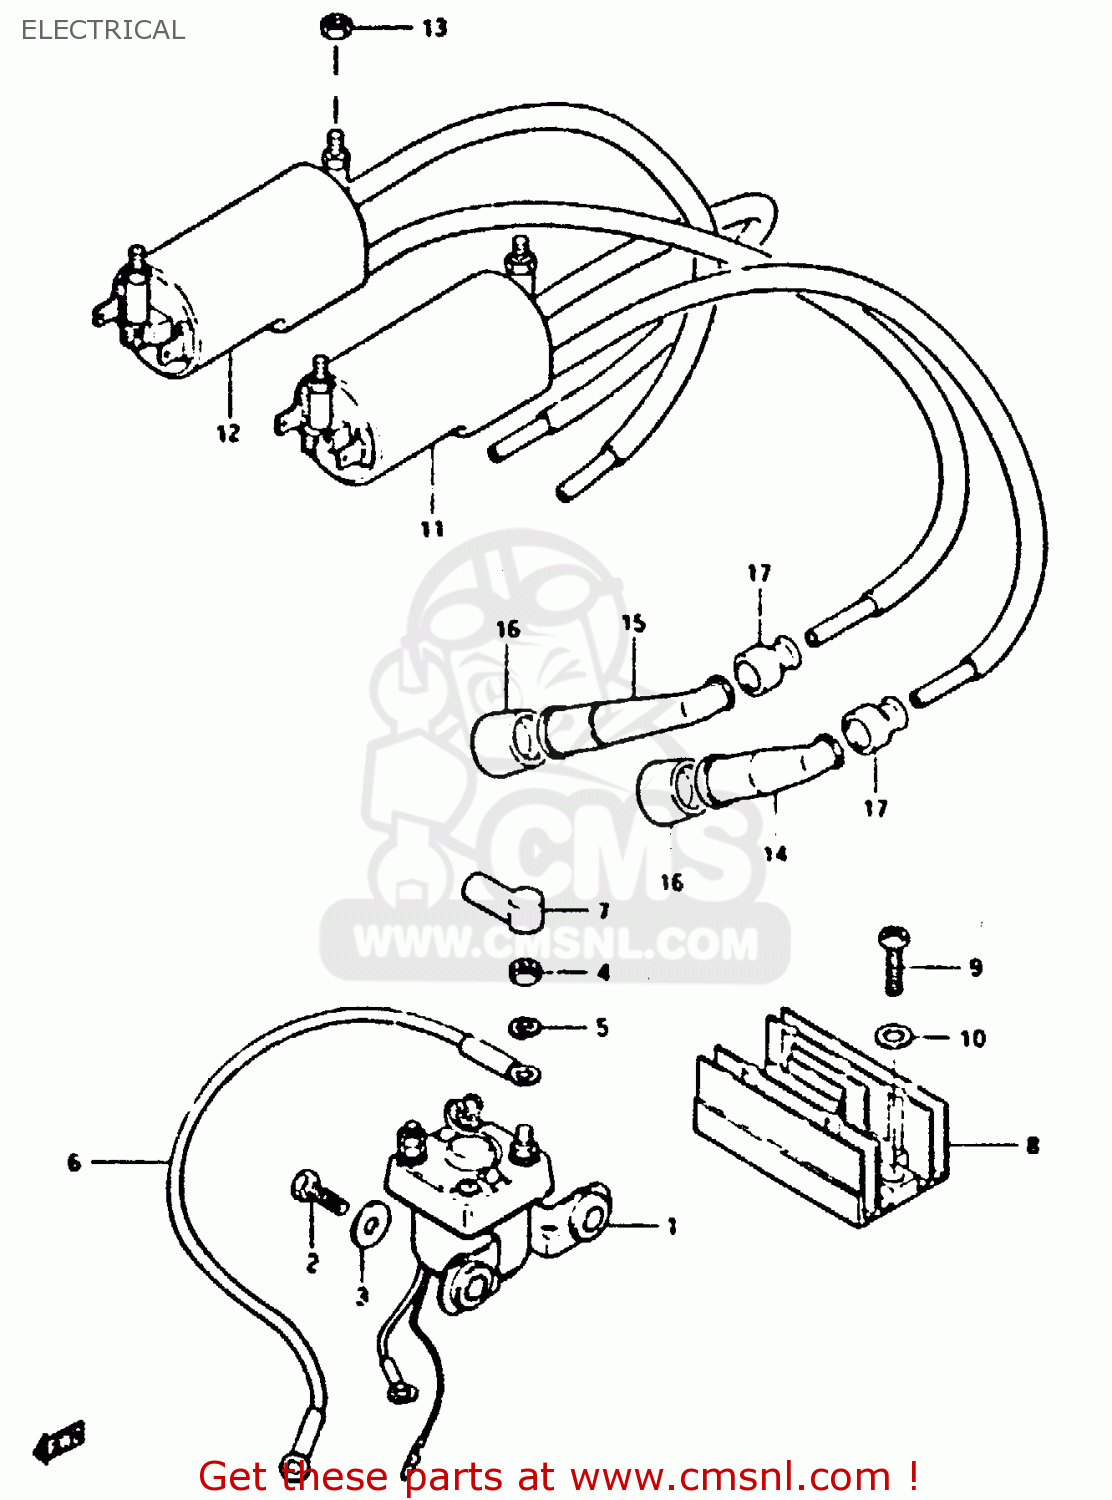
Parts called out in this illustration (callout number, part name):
1	RELAY,STARTER SWITCH
2	BOLT, UPPER
3	WASHER
4	NUT 6MM
5	LOCK WASHER
6	WIRE,STARTER MOTOR LEAD
7	CAP,STARTER RELAY
8	RECTIFIER ASSEMBLY
9	SCREW
10	WASHER
11	COIL ASSEMBLY,IGNITION
12	COIL ASSEMBLY,IGNITION
13	NUT
14	CAP,SPARK PLUG
15	CAP ASSY,SPARK PLUG
16	SEAL,SPARK PLUG
17	SEAL,SPARK PLU
